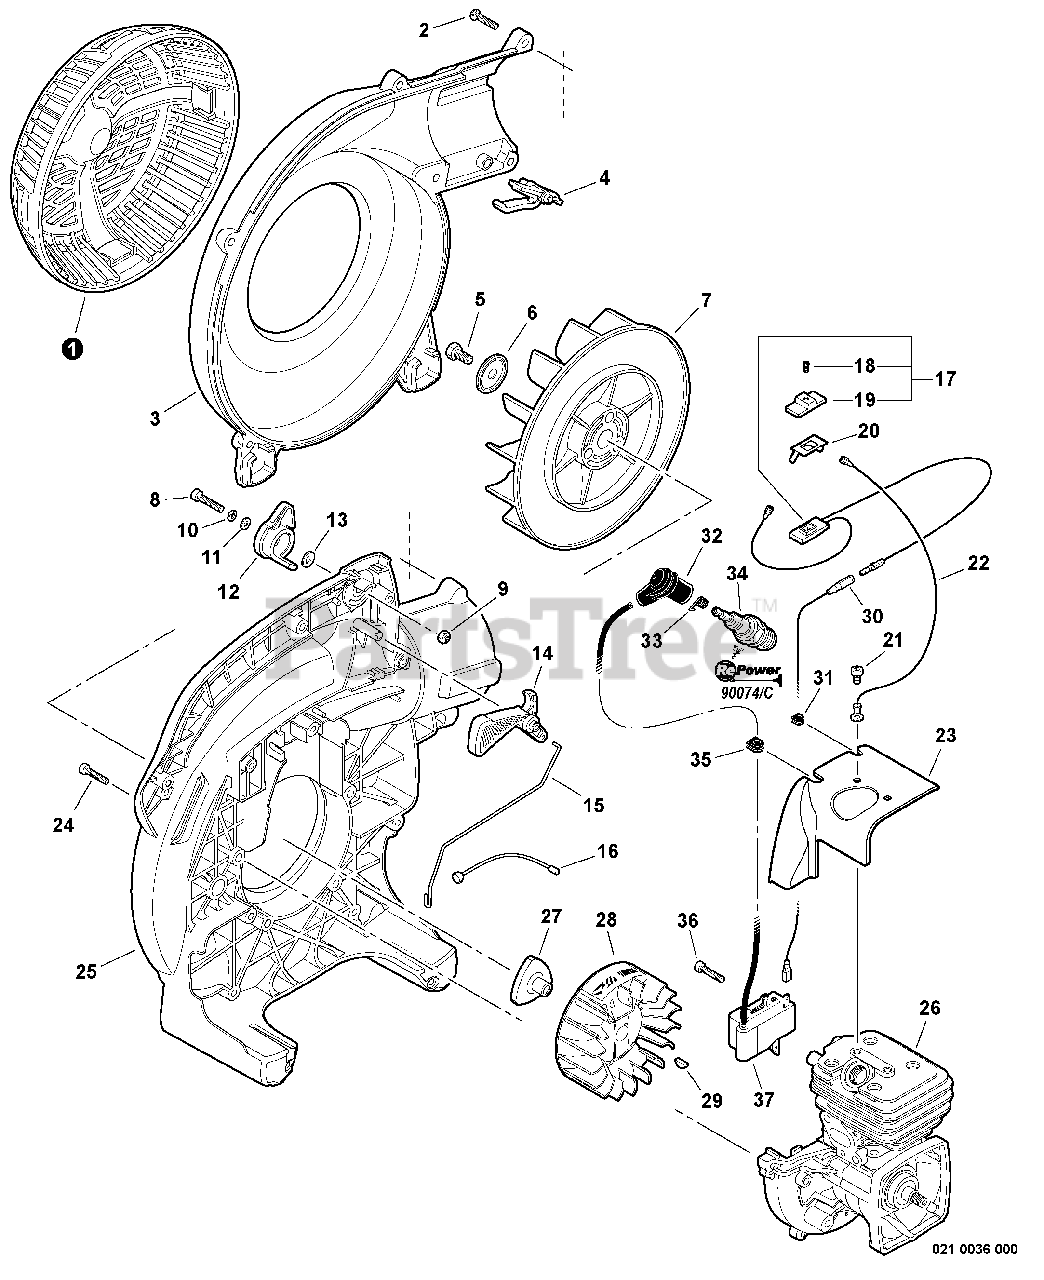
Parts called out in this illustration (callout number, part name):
1	GUARD, DEBRIS
2	SCREW - 5X20
3	COVER, FAN - LEFT
4	LOCK, TUBE
5	BOLT - 8X14
6	WASHER - CUP
8	SCREW - 5X25
9	LOCKNUT - 5
10	LOCKWASHER - 5
11	WASHER - 5
12	LEVER, THROTTLE
13	WASHER - 5
14	TRIGGER, THROTTLE
15	ROD, THROTTLE
16	CABLE, THROTTLE
17	SWITCH, IGNITION
18	SCREW - 3X10
19	KNOB, SWITCH - ORANGE
20	TERMINAL - GROUND
21	SCREW - 5X8
22	LEAD - GROUND
23	SHIELD, CYLINDER
24	SCREW - 4X20
25	COVER, FAN - RIGHT
26	SHORT BLOCK -- SB1104
27	HUB, FAN
28	FLYWHEEL
30	LEAD - IGNITION
32	CAP, SPARK PLUG
33	TERMINAL, SPARK PLUG CAP
34	SPARK PLUG -- BPM-8Y
34	SPARK PLUG -- BPMR-8Y
36	SCREW - 4X20
37	COIL, IGNITION
38	RePower TUNE-UP KIT
